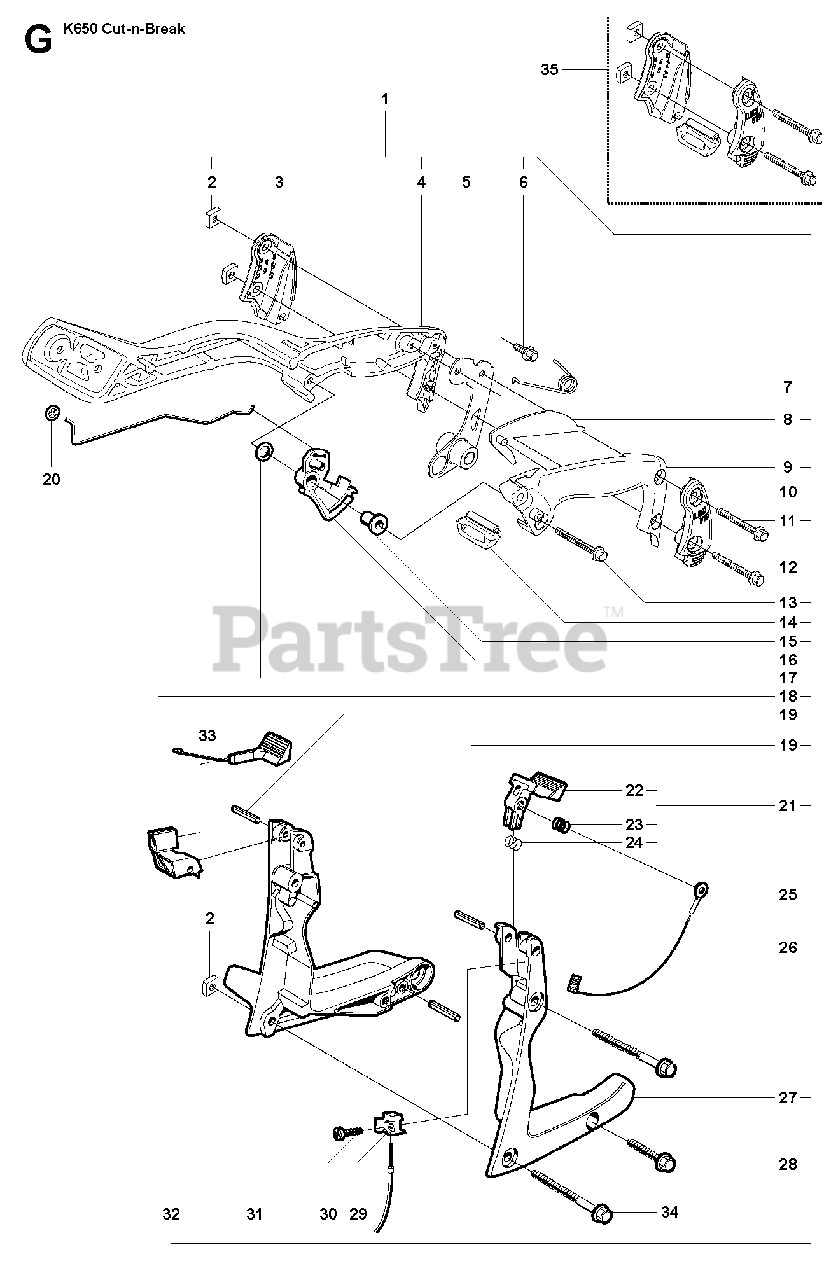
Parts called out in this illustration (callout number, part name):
1	HANDLEIncl. 2 - 19, 21, 25 - 32
5	ANTIVIBRATION ELEMENT
6	SCREW EHHFM
7	TORSION SPRING
21	SWITCHIncl. 22, 23, 24
30	SCREW CCRPANT
